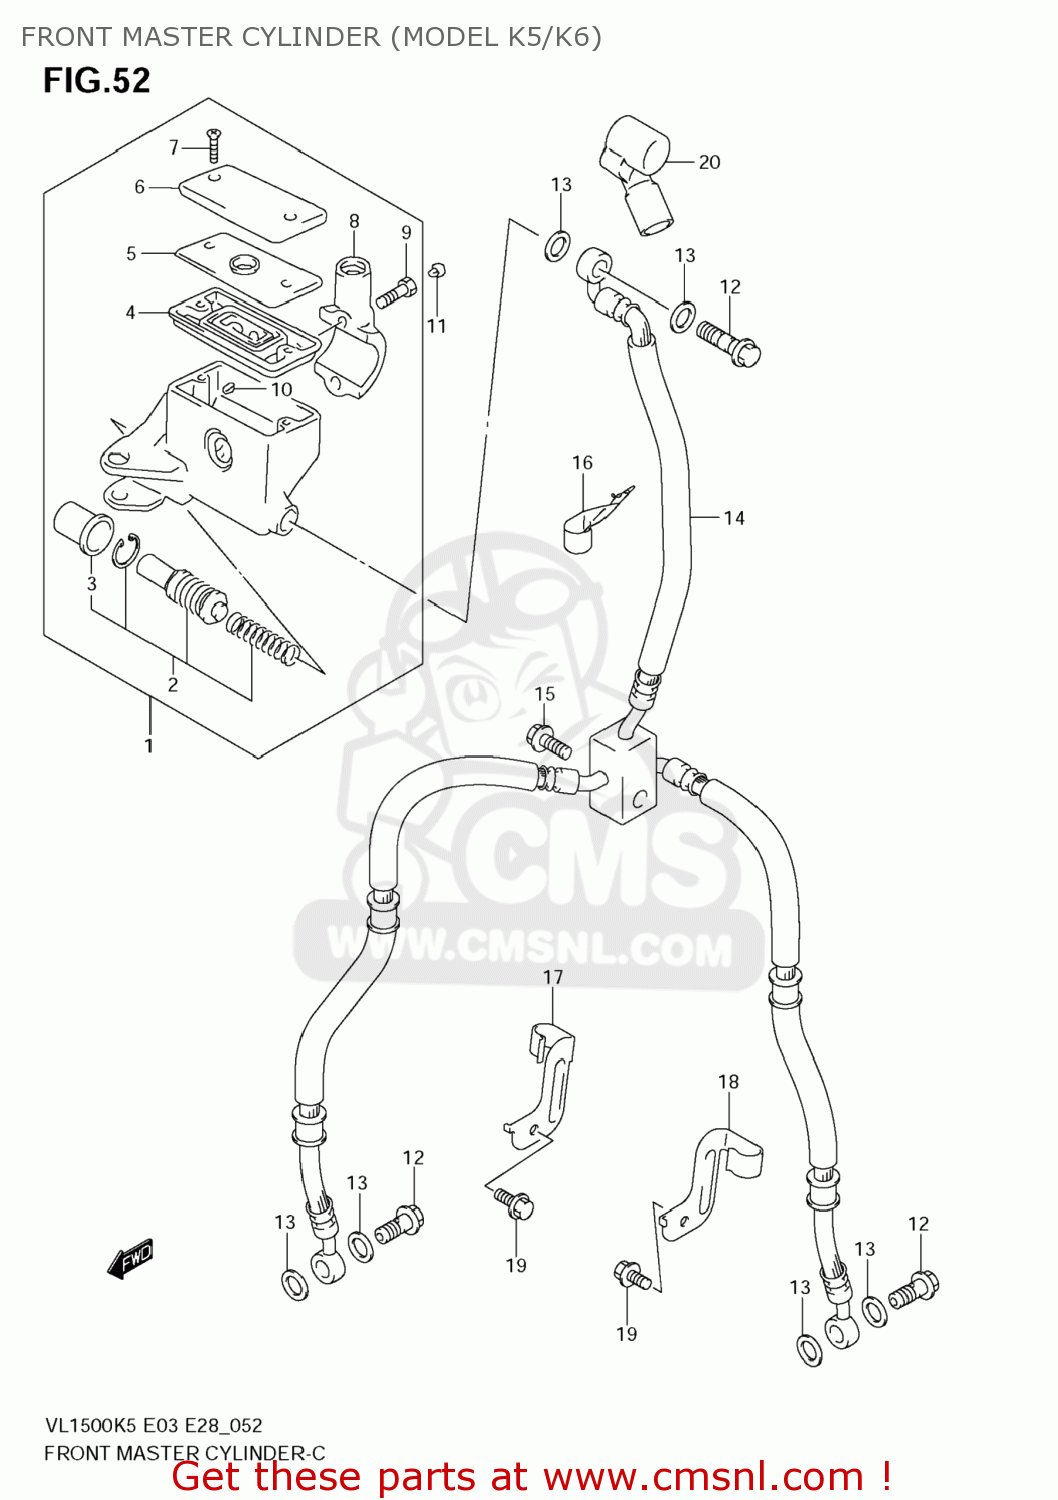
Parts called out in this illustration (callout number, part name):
1	CYLINDER ASSY,FR MASTER
2	PISTON & CUP SET
3	BOOT
4	5
5	PLATE,DIAPHRAGM
6	CAP
7	SCREW
8	HOLDER
9	BOLT
10	PROTECTOR
11	CAP(OD:10)
12	BOLT UNION
13	WASHER(10X15X1.5)
14	HOSE,FR BRAKE
15	BOLT(6X25)
16	CLAMP,FR BRAKE HOSE
17	CLAMP,FR BRAKE HOSE,R
18	CLAMP,FR BRAKE HOSE,L
19	BOLT(6X12)
20	BOOT,MASTER CYLINDER
